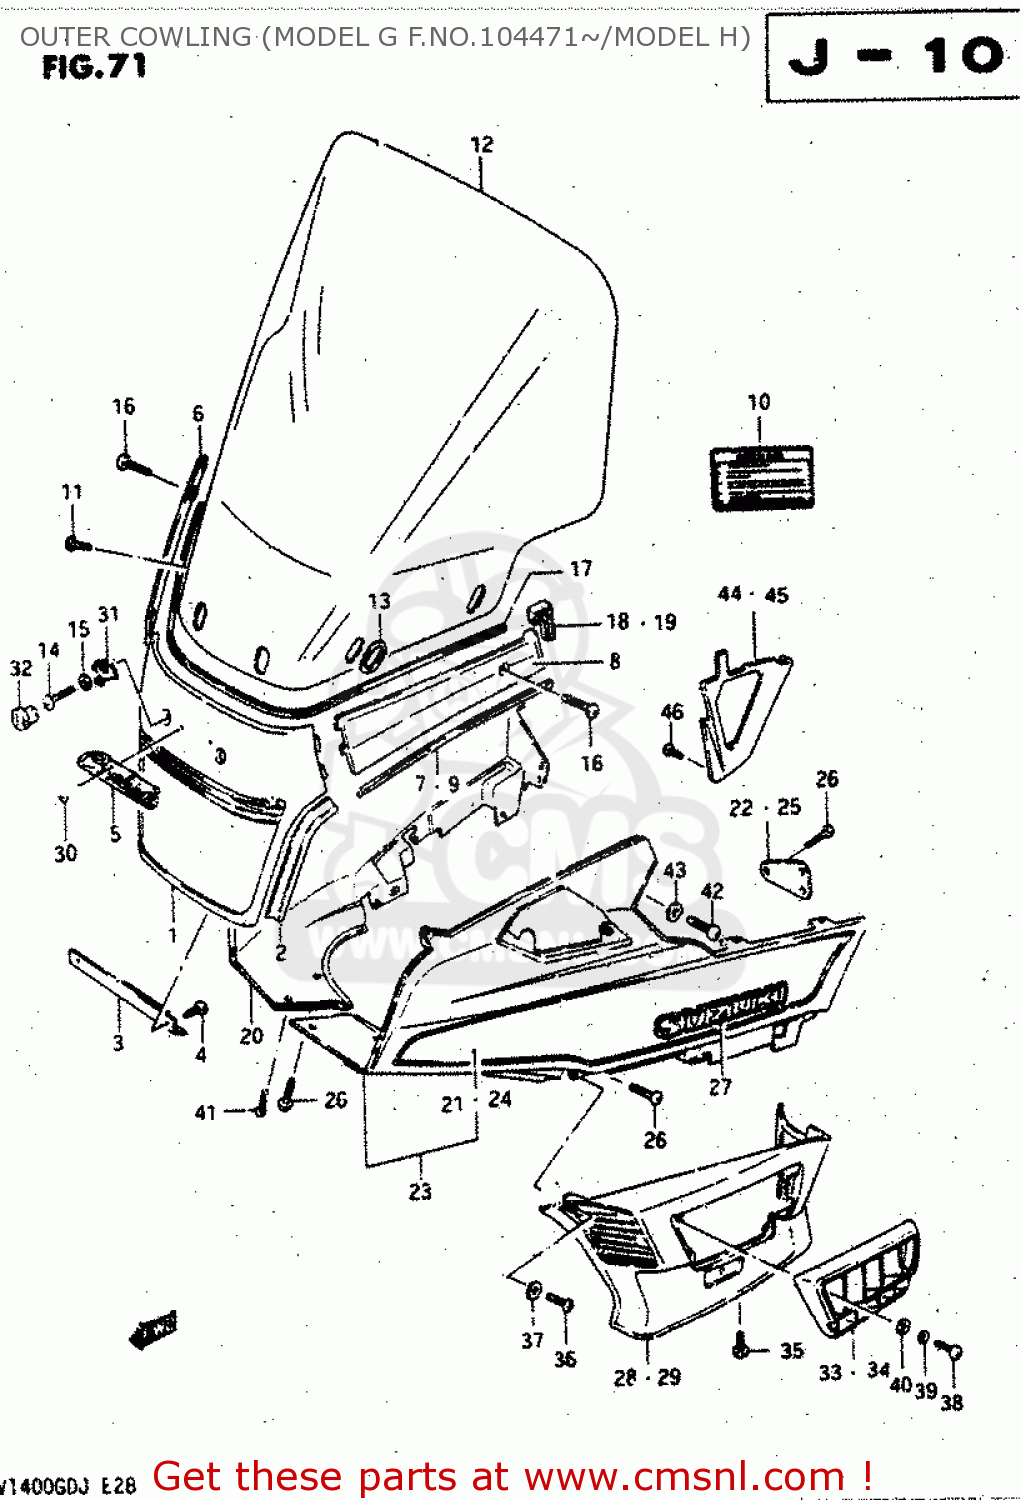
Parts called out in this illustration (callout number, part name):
1	COVER,COWLING,FRONT,CENTER
2	MOLDING,FRONT COVER,LOWER
3	BRACKET,FRONT,CENTER,UNDER
4	SCREW
5	EMBLEM,COWLING,FRONT
6	COVER,COWLING,FRONT,RIGHT
7	MOLDING,FRONT COVER SIDE
8	COVER,COWLING,FRONT,LEFT
9	MOLDING,FRONT COVER SIDE
10	LABEL (WARNING SCREEN)
11	SCREW
12	SCREEN ASSY,COWLING
13	WASHER,SCREEN
14	SCREW
15	WASHER
16	SCREW
17	SEAL,FRONT COVER,CENTER
18	CAP,COWLING FRONT COVER END
19	CAP,COWL FR COVER END,L
20	BODY,COWLING,RIGHT
21	TAPE SET, RH
22	BRACKET,COWLING BODY,RIGHT
23	BODY,COWLING,LEFT
24	TAPE SET, LH
25	BRACKET,COWLING BODY,RIGHT
26	SCREW
27	EMBLEM,COWLING SIDE,LEFT
28	COVER ASSEMBLY,COWLING
29	COVER ASSEMBLY,COWLING SIDE,LEFT
30	SCREW
31	PLATE,FRONT COVER LOCK
32	CAP,FR COVER
33	LOUVER,SIDE COVER,RIGHT
34	LOUVER,SIDE COVER,LEFT
35	SCREW (M6X1X16)
36	SCREW
37	WASHER (4.3X13X0.80)
38	SCREW
39	LOCK WASHER
40	WASHER
41	SCREW
42	SCREW
43	WASHER
44	UNDER COVER, FRAME
45	COVER,COVER FRAME,UPPER
46	SCREW
